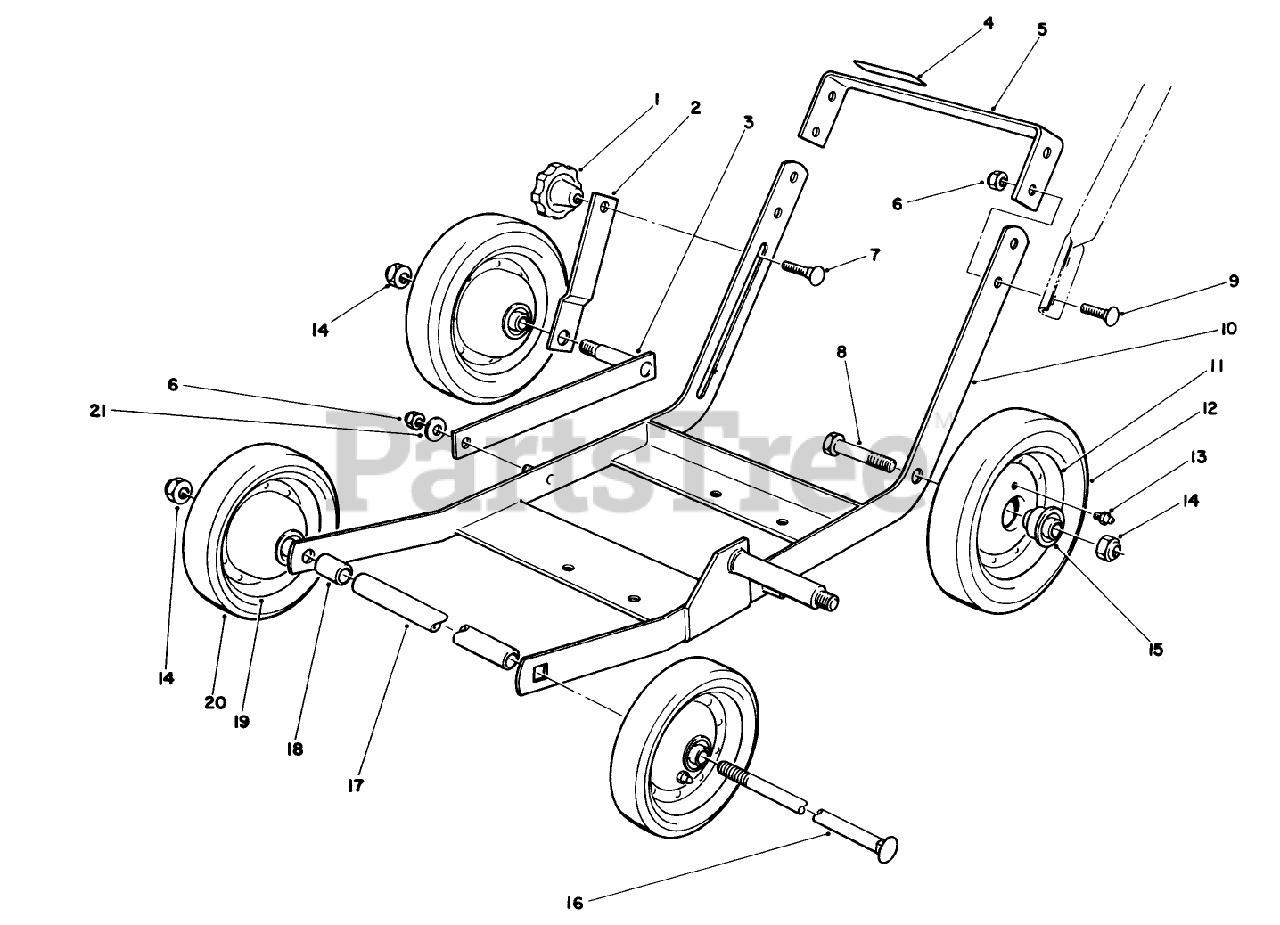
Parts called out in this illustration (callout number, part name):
3	BAR WA *RO
6	NUT-LOCK, NI
7	SCREW-CARR
8	SCREW-HH
9	SCREW-CARR
13	FITTING-GREASE
14	NUT-LOCK, NI
19	WHEEL ASM 7 IN.
21	WASHER-FLAT
